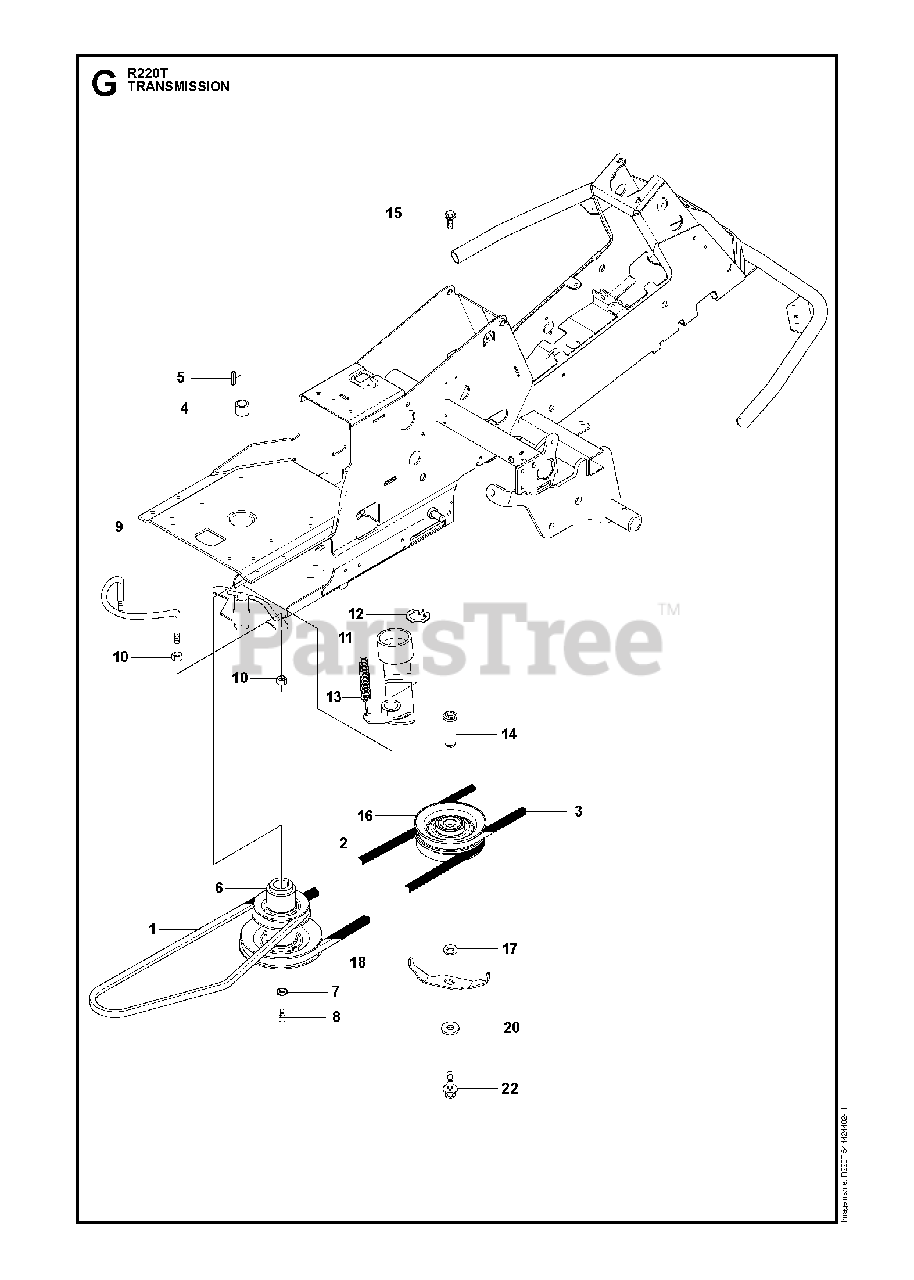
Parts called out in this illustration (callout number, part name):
1	BELT
2	BELT
3	BELT
9	Belt Guide
10	NUT
12	RETAINING RING SGA 25
14	SHAFT
18	BELT GUIDE
22	BOLT
